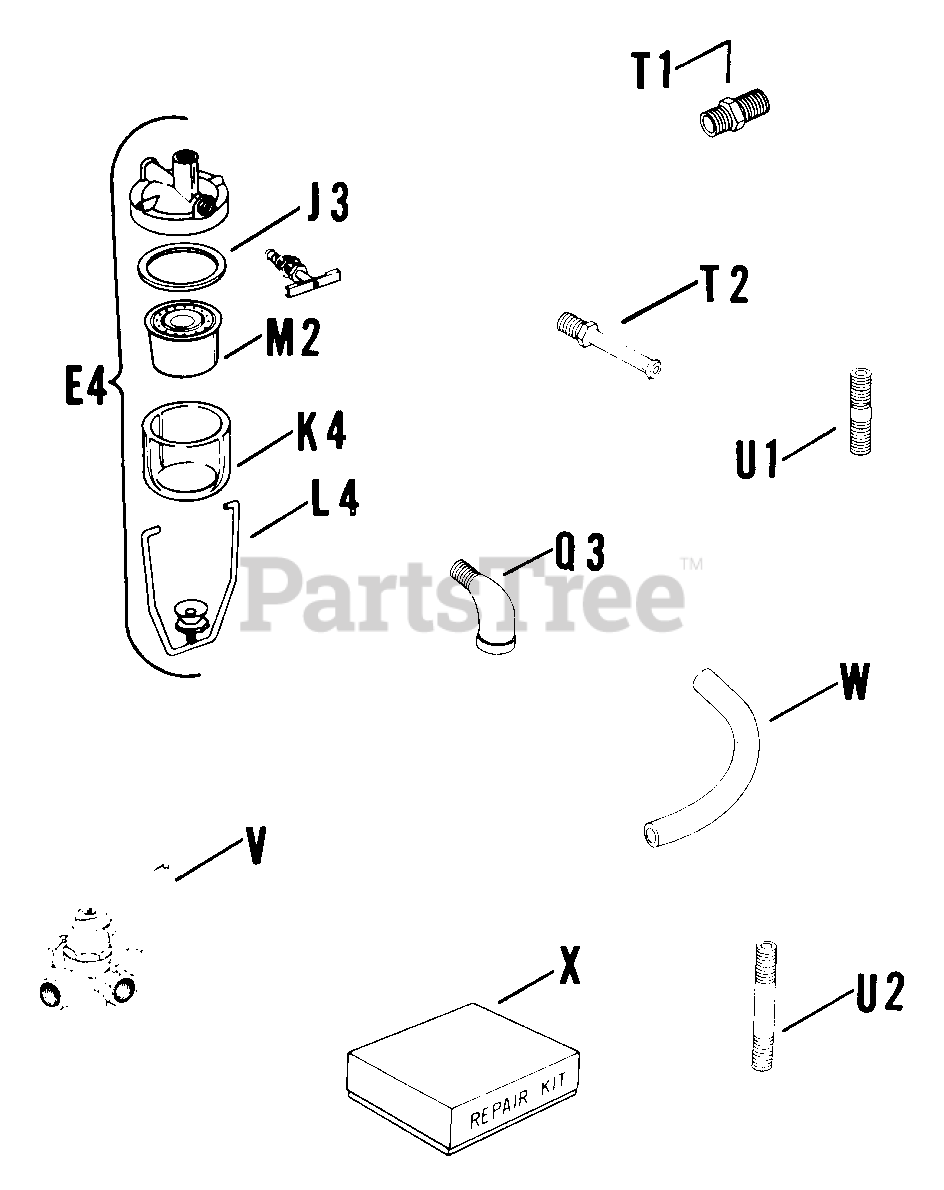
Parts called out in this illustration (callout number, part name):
Q3	ELBOW - USE 25 054 10
T1	CONNECTOR
U1	NIPPLE, PIPE 1/8 X 3/4 USE 25 136 23-S
X	KIT, FUEL PUMP REPAIR - DISC.
